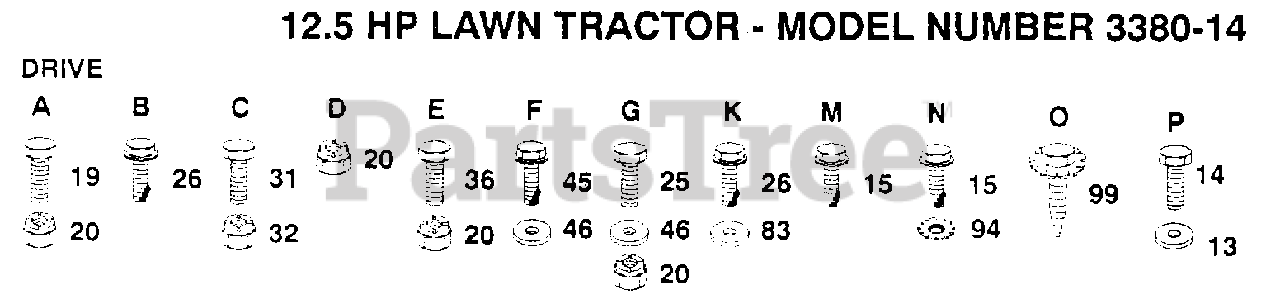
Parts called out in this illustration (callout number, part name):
13	LOCKWASHER
14	SCREW LT
15	SCREW
19	BOLT
25	BOLT
26	SCREW
31	BOLT
45	SCREW
46	WASHER
94	LOCKWASHER
